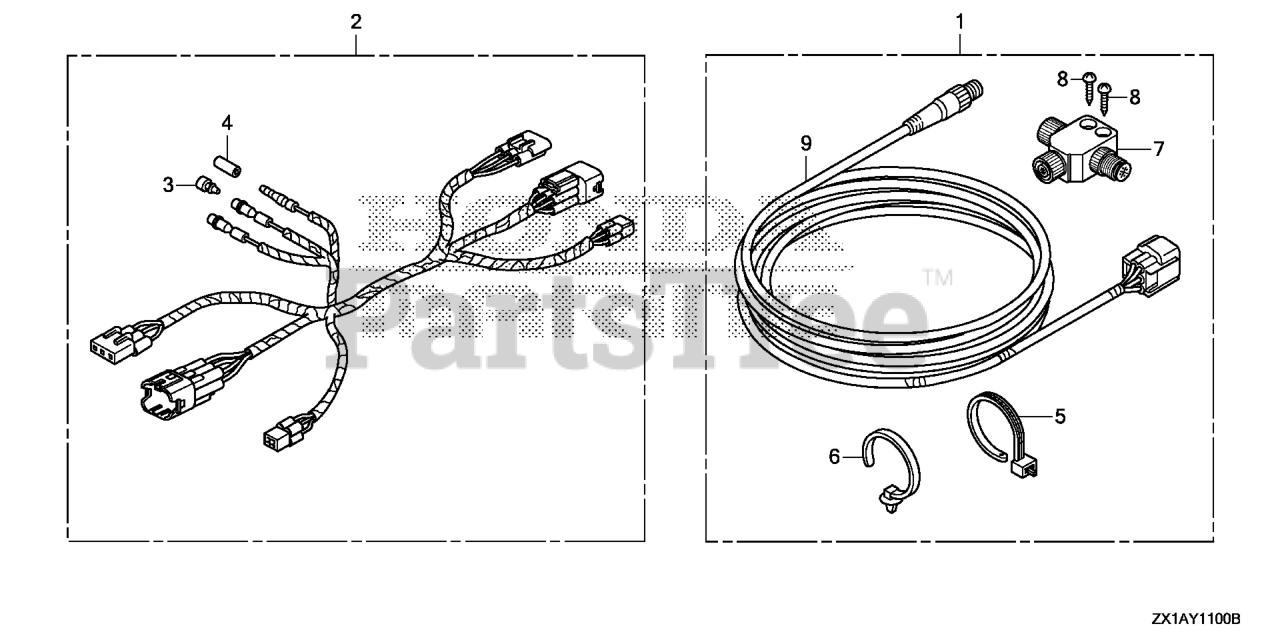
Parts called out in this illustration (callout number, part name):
1	KIT, CABLE (6FT) (NMEA)
1	CABLE KIT, INTERFACE
2	HARNESS ASSY., REMOTE CONTROL SUB (ENGINE NO.)
3	PLUG, CONNECTOR (INNER) (TROLLING CONTROL)
4	PLUG, CONNECTOR (OUTER) (ENGINE NO.)
5	TIE, CABLE
6	CLIP, HARNESS BAND (155.3MM) (BLACK)
7	CONNECTOR (T)
8	SCREW, TAPPING (4X25)
9	CABLE ASSY., INTERFACE (6FT)
